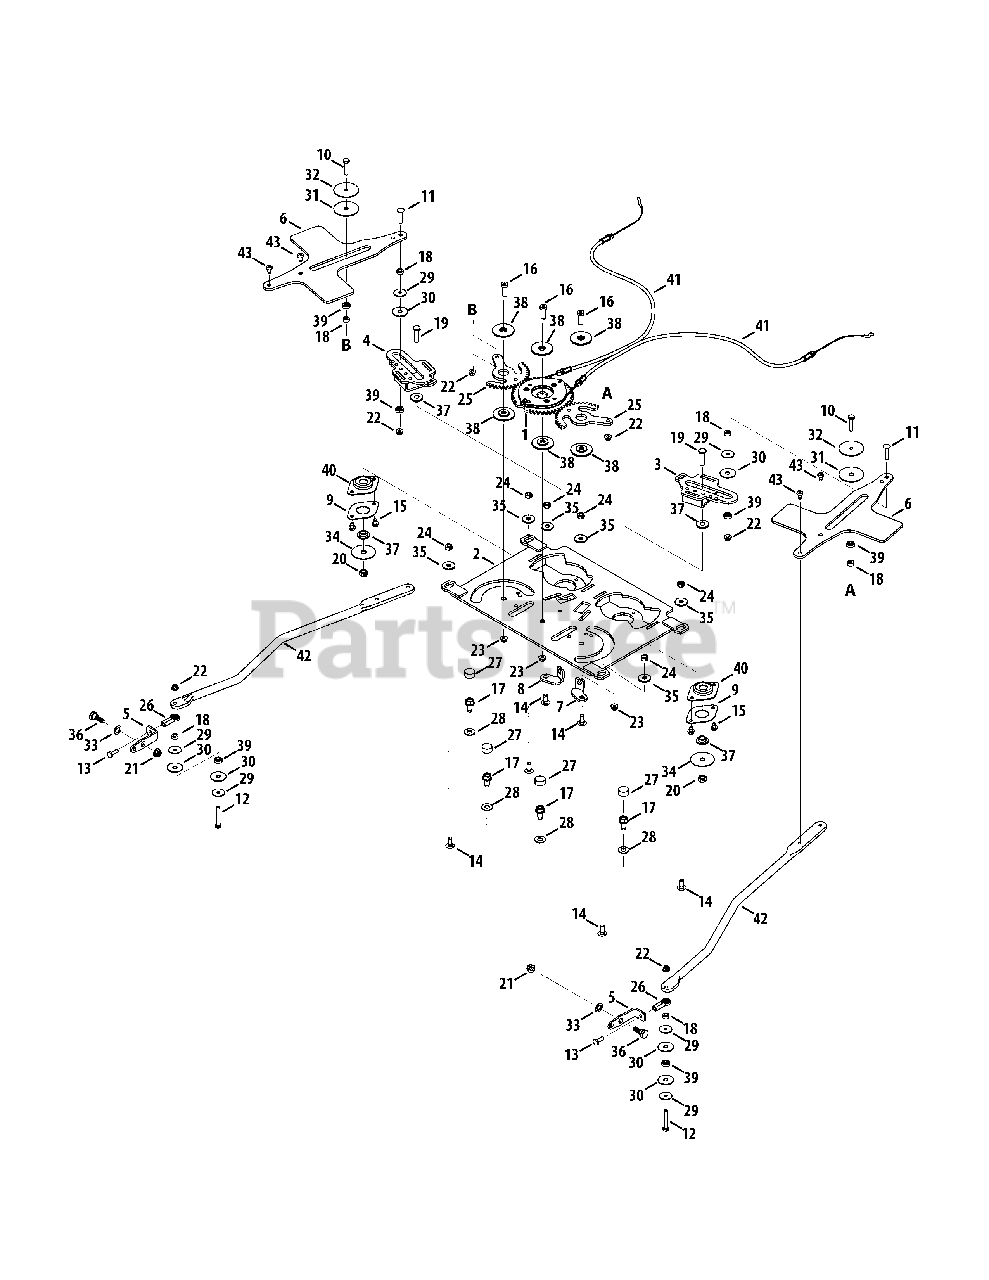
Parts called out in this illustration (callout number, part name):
1	Pump Control Gear
2	Pump Control Mounting Plate
3	Pump Control Cam Assembly, RH
4	Pump Control Cam Assembly, LH
5	Pump Control Bracket
6	Pump Steering Arm Actuator
7	Steering Cable Bracket
8	Steering Cable Bracket
9	Retainer Bearing Plate
10	Hex Cap Screw, 1/4-20 x 1.25
11	Carriage Screw, 1/4-20 x 1.25
12	Hex Cap Screw, 1/4-20 x 1.75
13	Hex Cap Screw, 1/4-28 x .75
14	Carriage Bolt, 5/16-18 x .75
15	Hex Flange Screw, 1/4-20 x .500
16	Socket Head Screw, 3/8-16 x 1.00
17	Screw, 3/8-16 x .75
18	Spacer, .256 x .500 x .240
19	Hex Cap Screw, 3/8-16 x 1.25
20	Nut, 3/8-16, Hexlock
21	Nut, 5/16-18, Flangelock
22	Nut, 1/4-20, Flangelock
23	Nut, 3/8-16, Flnagelock
24	Nut, 5/16-18, Hexlock
25	Yoke Steering Gear
26	Rod End, 1/4-28
27	Slide Cap
28	Washer, .406 x .875 x .059
29	Washer, .255 x 1.00 x .060
30	Washer, .355 x 1.25 x .060
31	Washer, .356 x 2.00 x .060
32	Washer, .260 x 2.00 x .060
33	Washer, .469 x .75 x .060
34	Washer, .406 x 1.92 x .060
35	Washer, .345 x 1.00 x .100
36	Shoulder Screw, .437 x .268, 5/16-18
37	Shoulder Spacer, .38 x 1.00 x .31
38	Shoulder Spacer, .853 x .385 x .100
39	Ball Bearing, .250 x .625
40	Ball Bearing, .625
41	Transmission Link Control Cable
42	Pump Control Rod
43	Shoulder Screw, .342 x .335, 1/4-28
